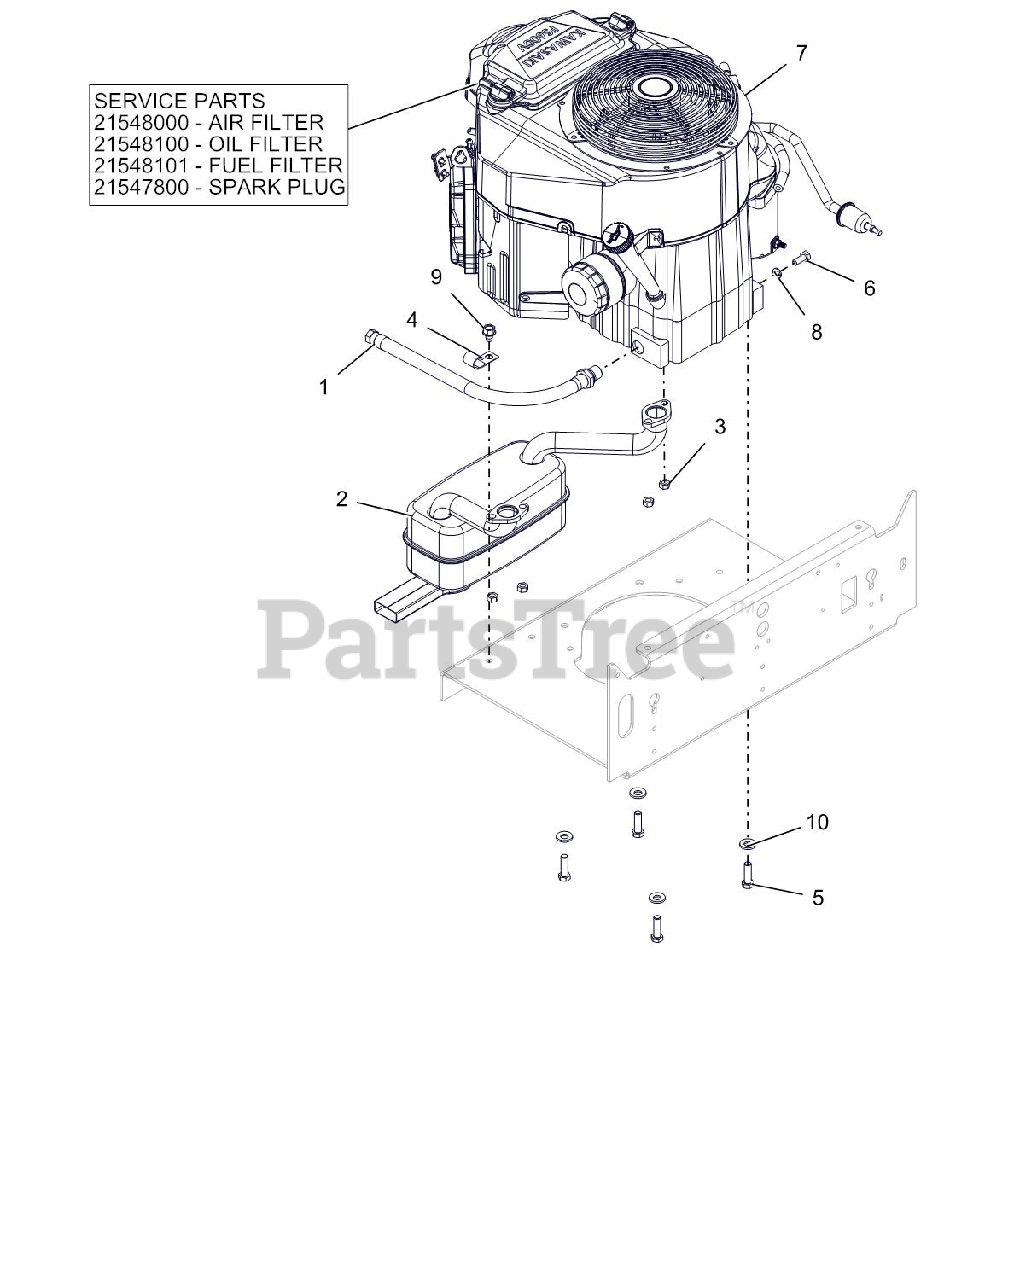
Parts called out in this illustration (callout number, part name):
1	HOSE, OIL DRAIN
2	MUFFLER, KAW FS691/730
3	NUT-LK-TOP M8-1.25 YWZC
5	BLT-HEX.38-16X1.25 G5YZ NYTORQ
6	@BLT-HEX M8-1.25X20 YWZC
7	ENGINE, KAWASAKI FS691
7	AIR FILTER, KAWASAKI FR
7	OIL FILTER, KAWASAKI FR
7	FUEL FILTER-KAWASAKI FR
7	SPARK PLUG, KAWASAKI FR
8	@WSHR-LK .31X.078 REG YWZC
9	@SCR-TAP .38-16X.50 HWH TR YWZ
10	WASHER, 3/8" SPRING DISC
